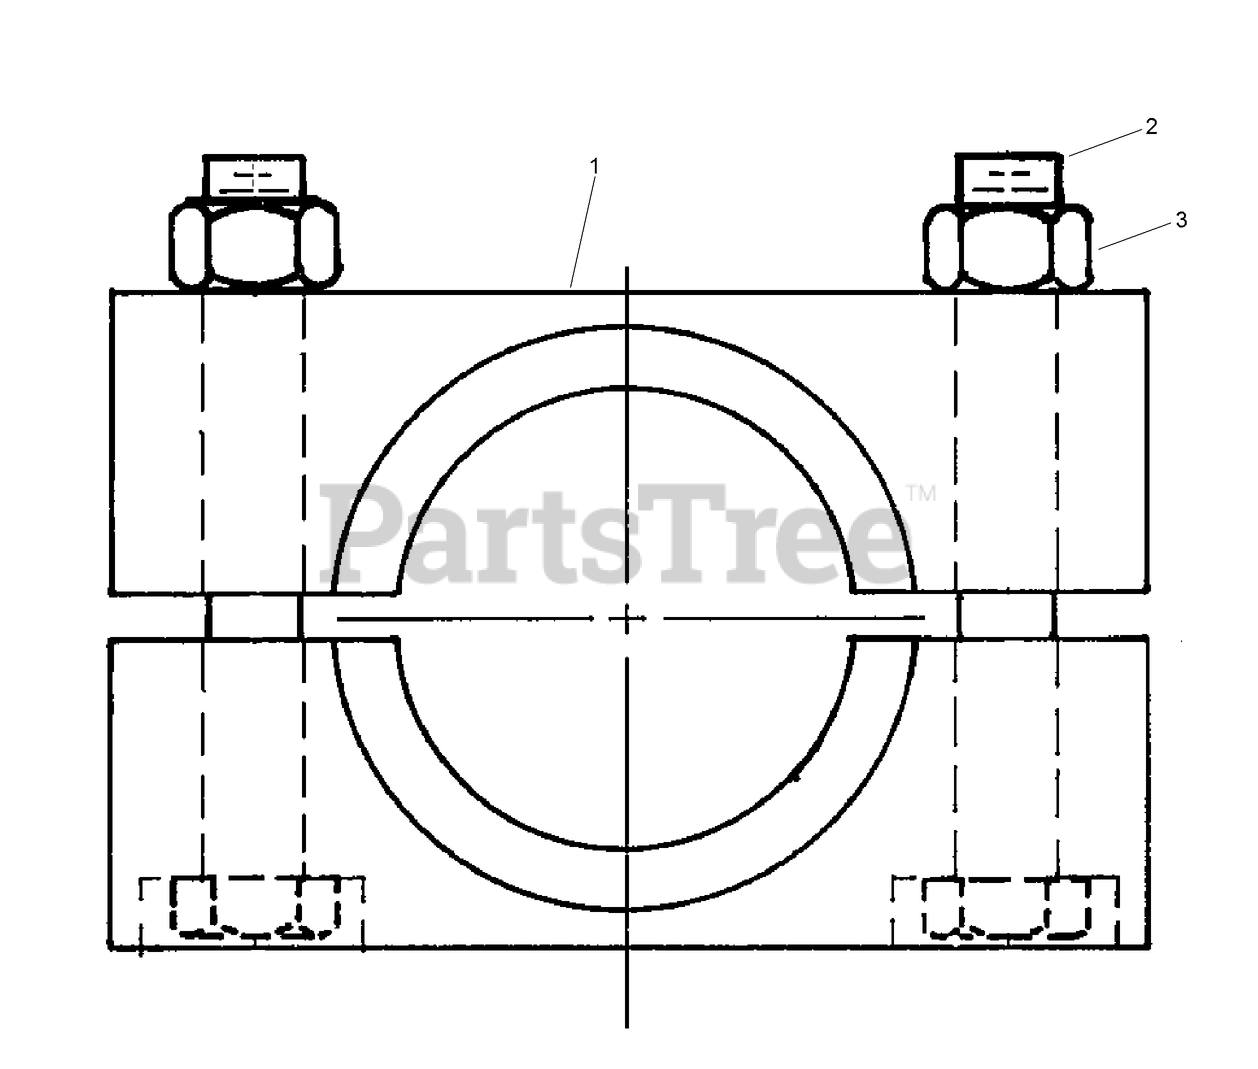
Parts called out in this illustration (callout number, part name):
1	BLOCK - Swing Cylinder Stop
2	BOLT-HH
3	NUT-HEX
